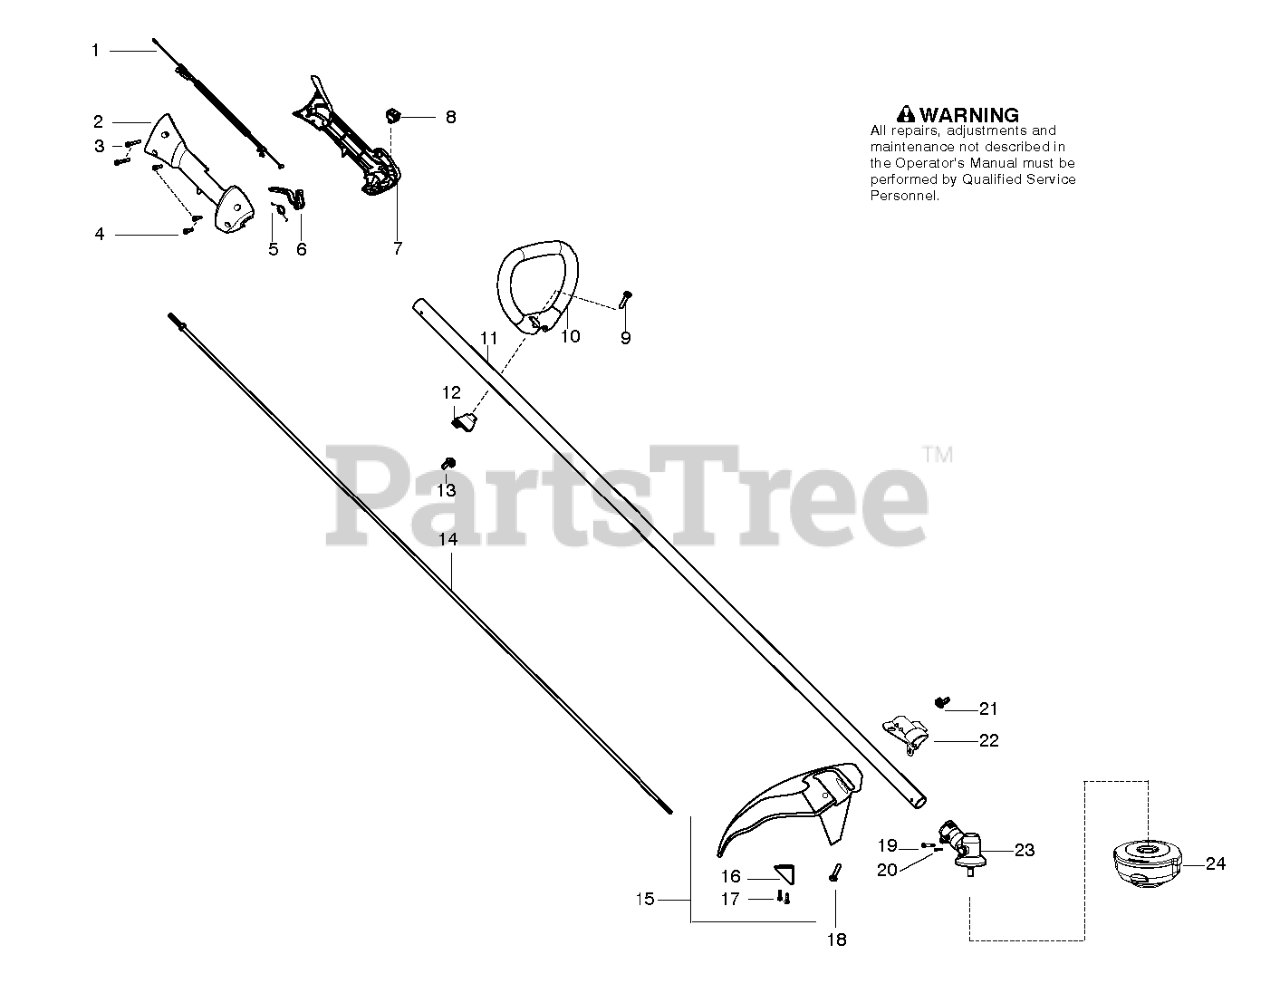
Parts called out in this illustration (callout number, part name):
1	ASSY-CABLE WIRE HARNESS
1	KIT-AIR BOX W/CABLE WIRE HARN
2	HOUSING-THROTTLE (RH)
4	SCREW M4 X 1.75 PT 16MM
5	SPRING TRIGGER
6	TRIGGER THROTTLE
7	HSG THROTTLE LH
8	KIT SWITCH
9	BOLT, TYPE 2
10	HANDLE ASSIST
11	KIT DRIVESHAFT SST
12	CLAMP ASSIST HANDLE
13	WINGNUT, TYPE 2
14	FLEXSHAFT 57"
15	KIT-SHIELD
16	LINE LIMITER 17"
18	BOLT, TYPE 2
19	SCREW - CARB. ADAPTOR
20	SCREW 8-16 X 9/16 (PLAS
21	WINGNUT, TYPE 2
24	TRIMMER HEAD T25
